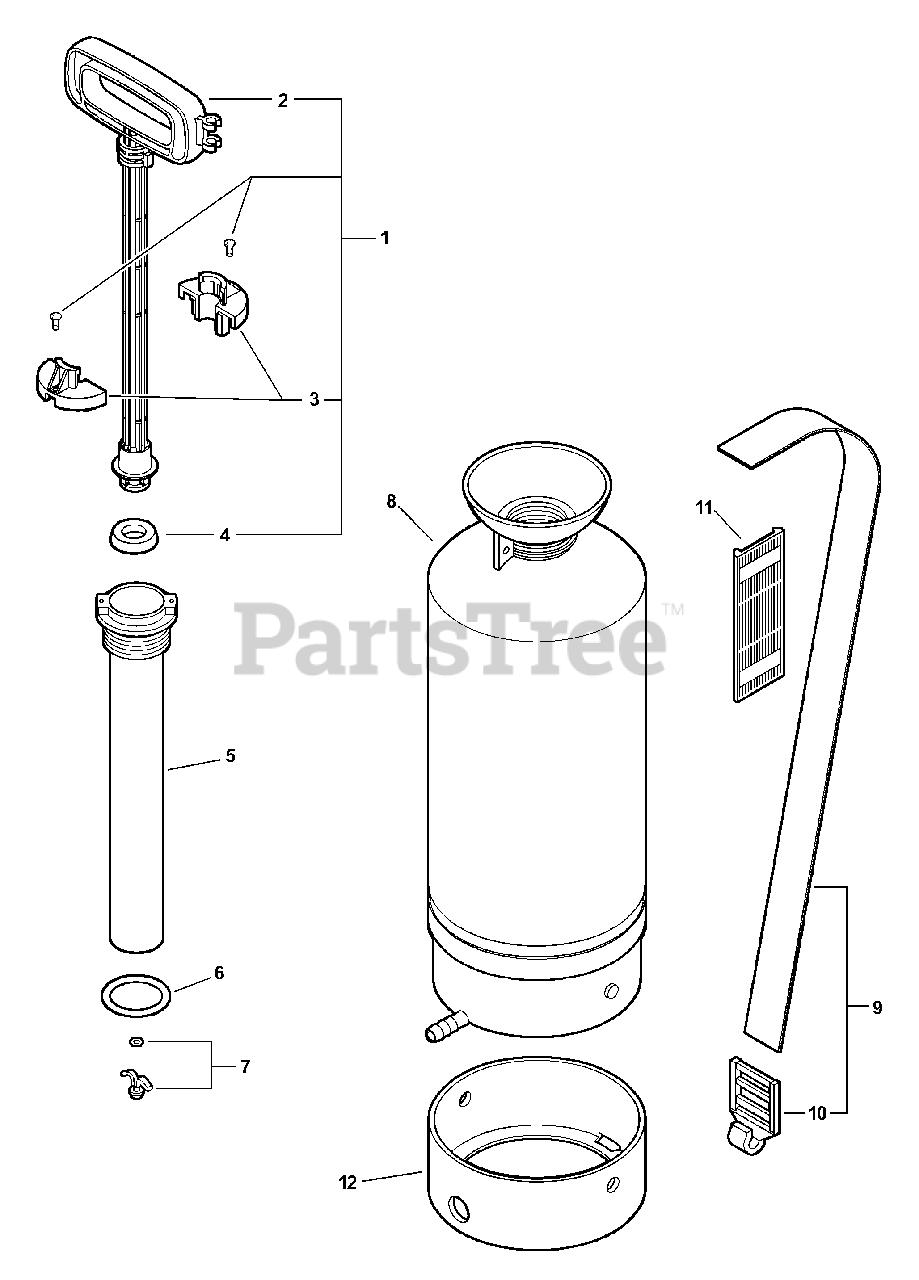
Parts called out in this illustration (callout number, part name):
1	PUMP HANDLE ASSY
2	HANDLE, PUMP
3	CAPS, PUMP HANDLE
4	PLUNGER, PISTON PUMP
5	TUBE, PUMP
6	O-RING
7	CHECK VALVE ASSY
8	TANK
9	STRAP ASSY
11	PAD, SHOULDER STRAP
12	BASE, TANK -- MS-20
12	BASE, TANK -- MS-35
